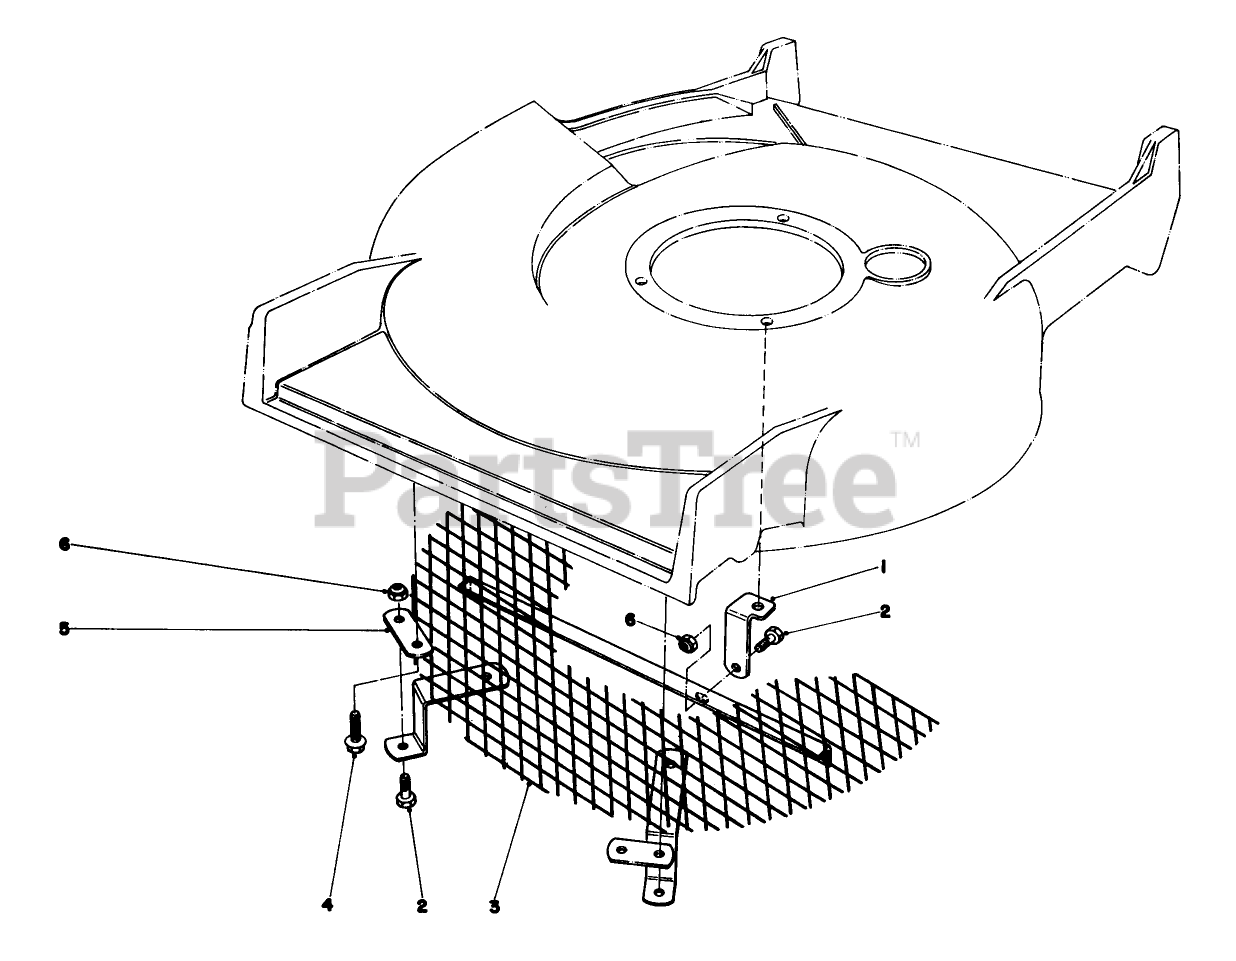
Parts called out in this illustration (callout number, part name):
2	SCREW-HH
4	SCREW-THD ROLL, HWH
6	NUT-LOCK, NI
